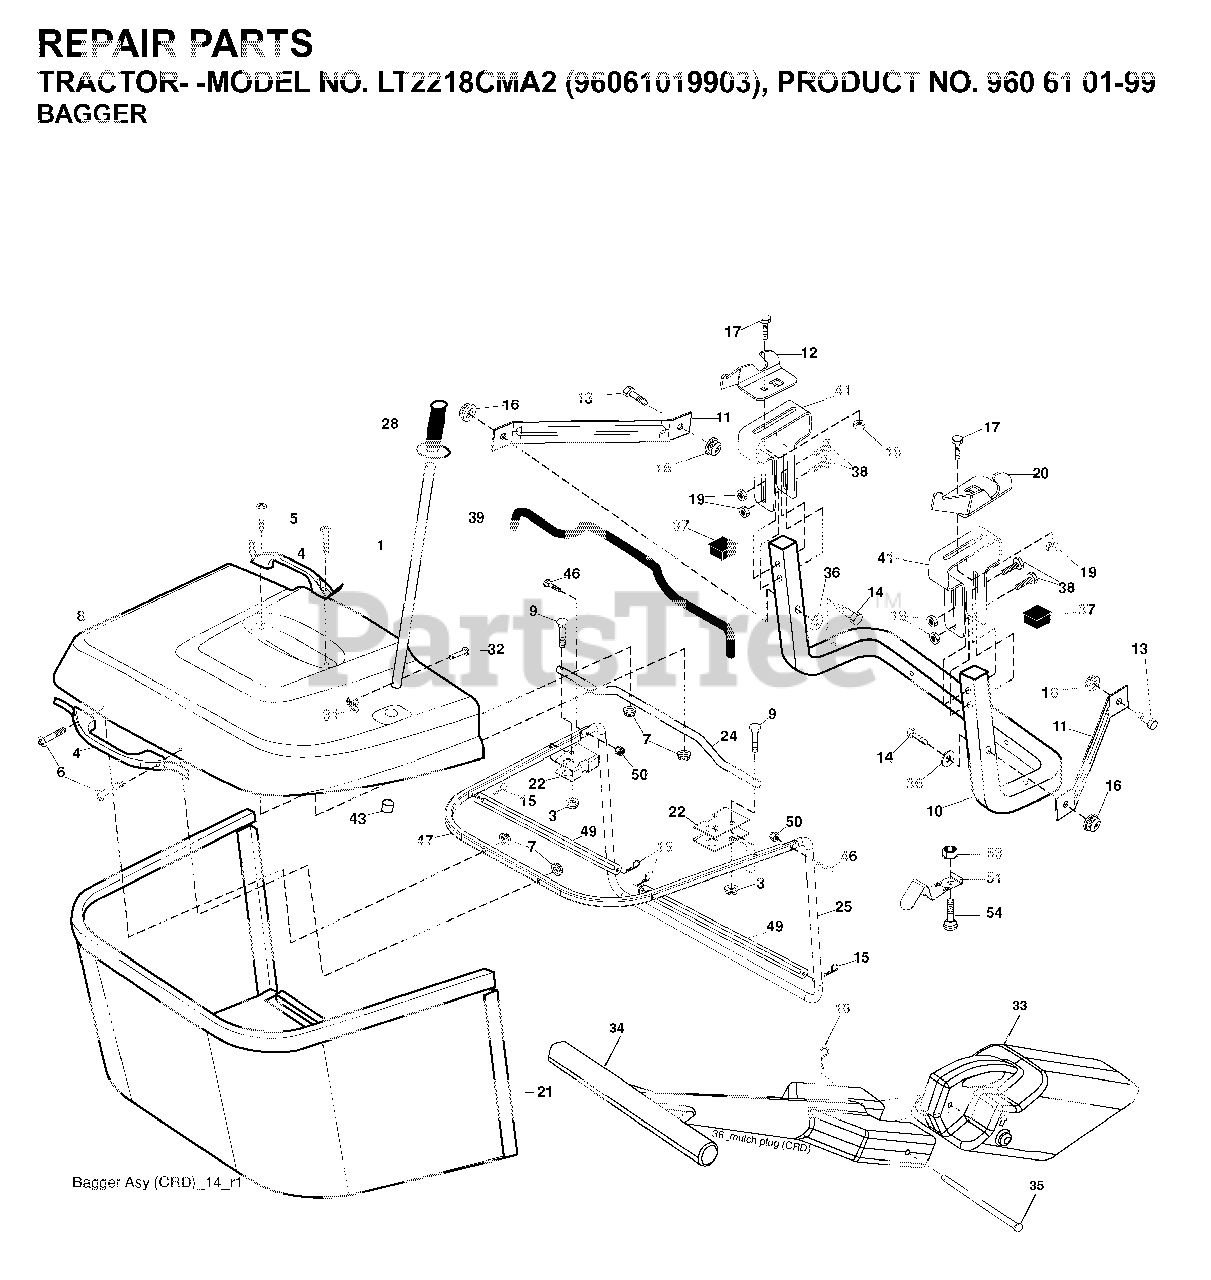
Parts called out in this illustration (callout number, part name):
1	TUBE HANDLE
3	NUT T
5	SCREW.PAN.HEAD
11	BRACKET
14	BOLT-HEX EAK
15	RETAINER-SPRNG RB
16	NUT LOCK FLG 3/8-16 UNC
17	BOLT
19	NUT LOCK HEX FLANGE 5/16-18
20	BRKT.PIVOT.RH.CRD
21	BAGGER.ASM.CRD.2007
22	BRACKET
24	TUBE
28	GRIP.HANDLE.BLACK
31	RETAINER CLIP
32	RIVET,DRILLED
33	MULCH PLUG, CTH150
35	PIN
38	BOLT.5/16-18X2.5
39	SEAL.BAGGER.CRD
41	BRKT, BAGGER
43	PLUG, TUBING END
46	BOLT.CARRIAGE.5/16-18
50	NUT.71038.31-18.HEX.NYLOCK
53	NUT
54	BOLT
